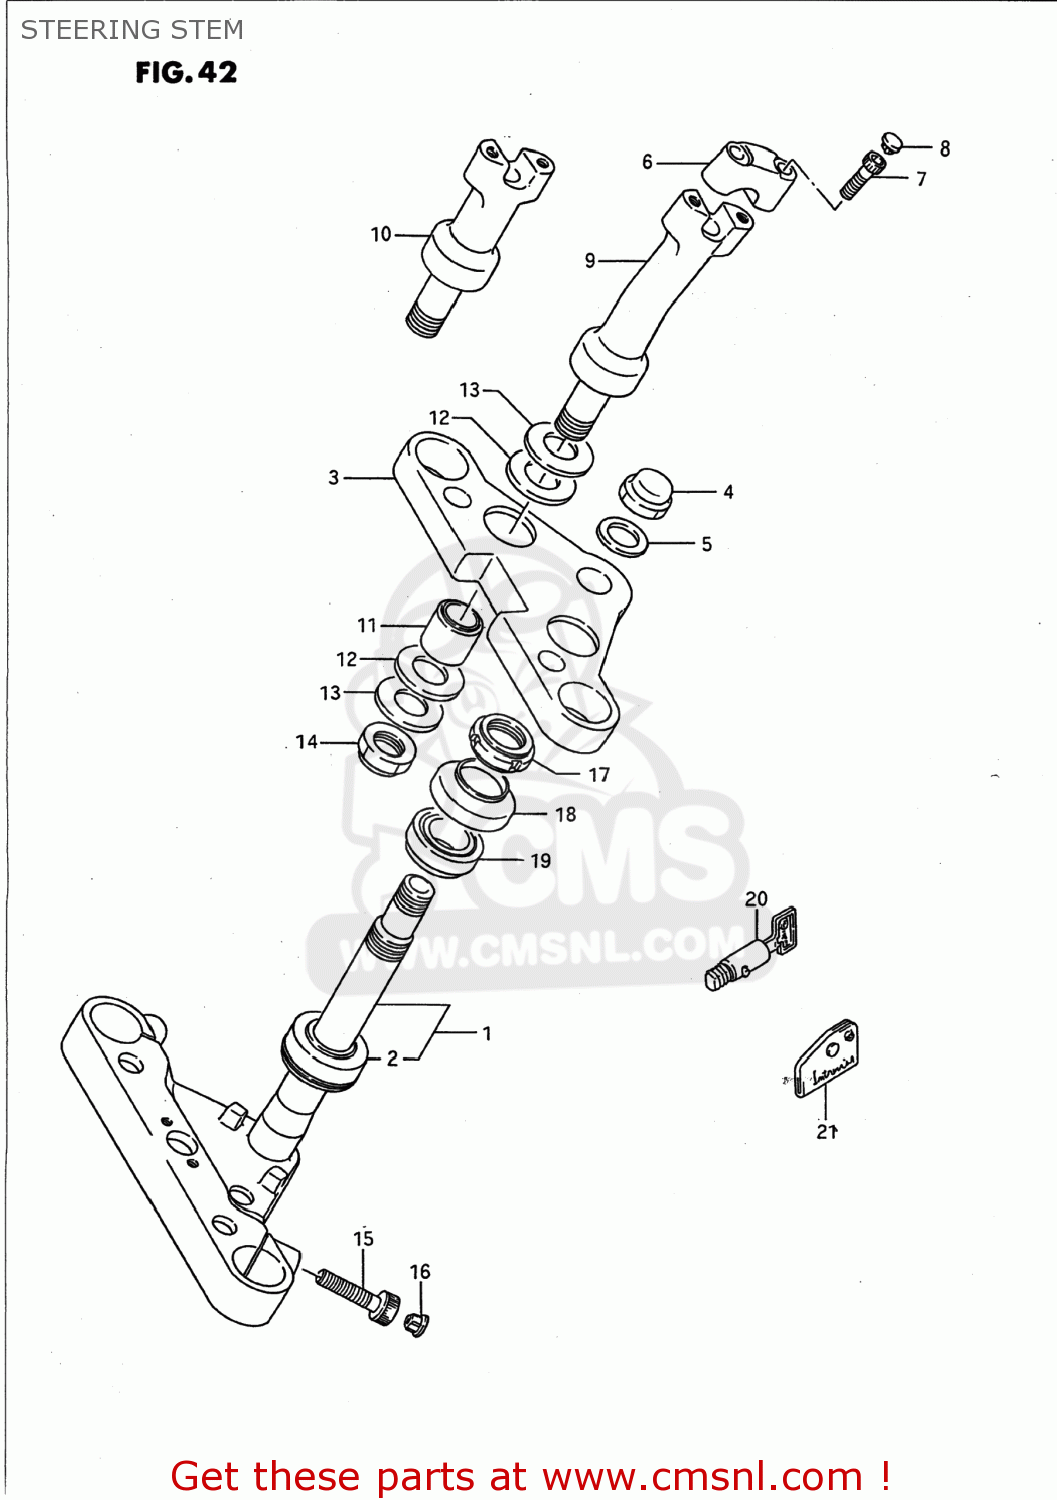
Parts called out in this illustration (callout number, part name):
1	STEM,STEERING
2	BEARING(30X55X17)
3	HEAD,STEERING STEM
4	NUT,CAP
5	WASHER
6	HOLDER,HANDLE UPR
7	BOLT, REAR (8X30)
8	CAP(OD:14.5)
9	HOLDER,HANDLE
10	HOLDER,HANDLE
11	CUSHION
12	SEAT,RUBBER
13	WASHER
14	NUT
15	BOLT
16	CAP(OD:12)
17	NUT,STEERING STEM(25X44X10)
18	SEAL,STEERING UPR DUST
19	TAPER,ROLLER BEARING
20	LOCK SET,STEERING
21	CASE,STEERING KEY
